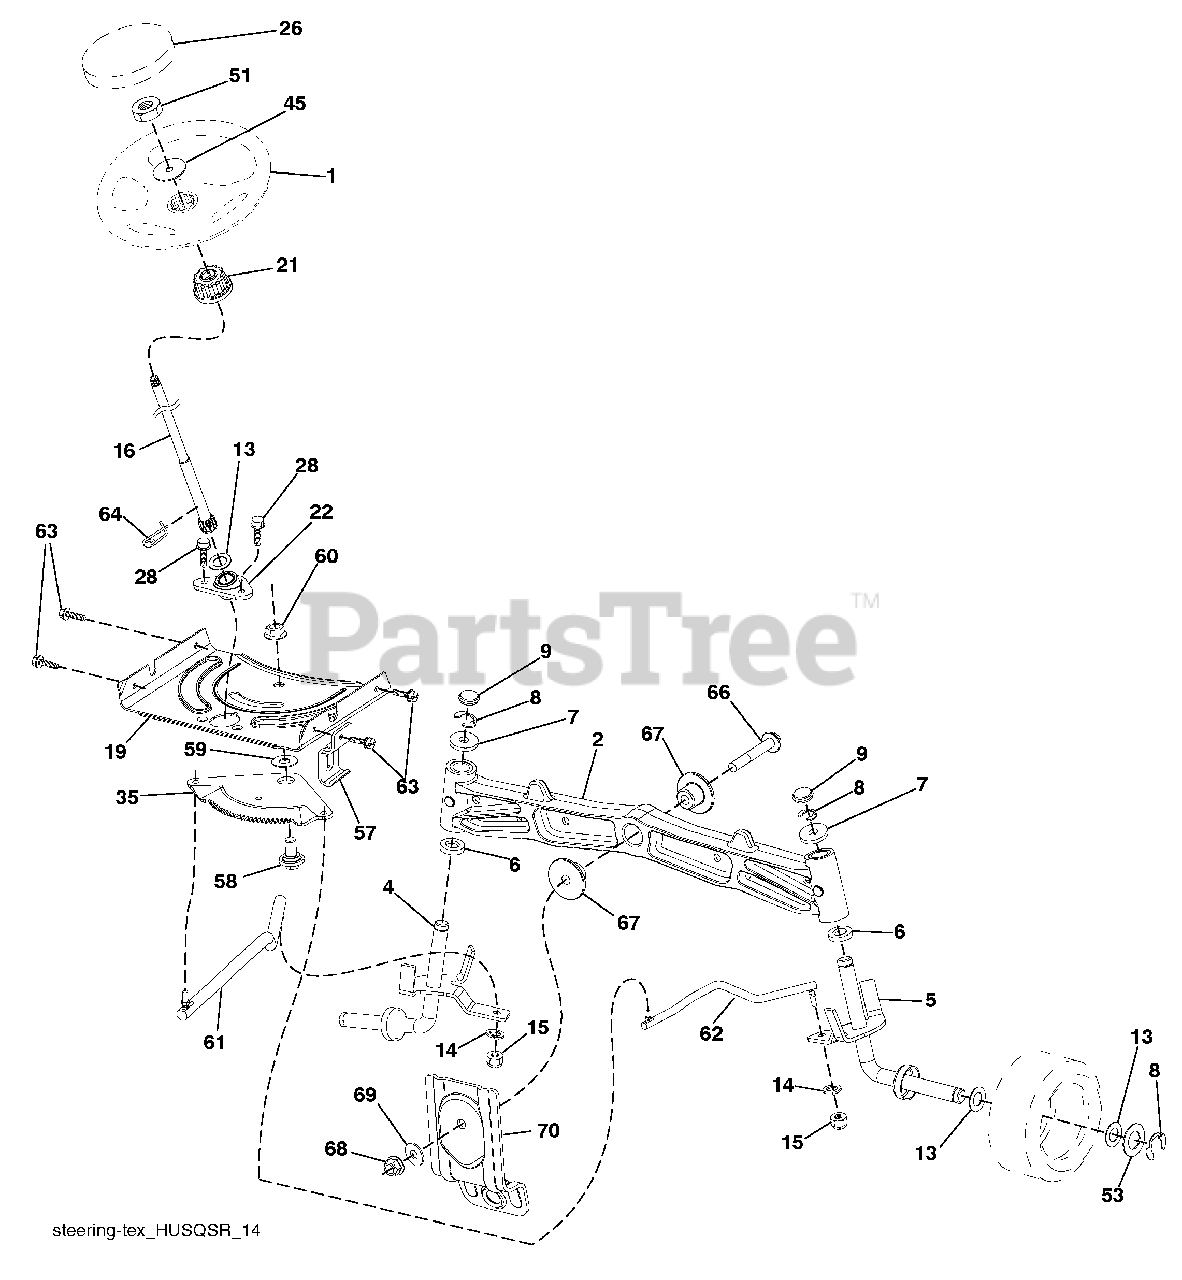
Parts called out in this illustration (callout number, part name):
1	Wheel, Steering
2	Axle Asm., Front
4	Spindle Asm., LH
5	Spindle Asm., RH
6	Bearing, Race Thrust Harden
7	Washer 25/32 x 1-5/8 x 16 Ga.
8	Ring, Klip #T5304-75
9	Cap, Spindle
13	Washer 25/32 x 1-1/4 x 16 Ga.
14	Washer, Lock Hvy Hlcl Spr 3/8
15	Nut, Crown Lock 3/8-24 unf
16	Shaft Steering
19	Plate Steering
21	Adapter, Wheel Steering
22	Strg. Supt. lower
26	Insert, Wheel Steering
28	Screw 3/8-16 x 3/4
35	Gear, Sector Plate
45	Washer 9/16 x 2-3/8 x 12 Ga.
51	Nut Hex Jam Toplock 1/2-20 unf
53	Washer Hardened .793 x 1.637 x .060
57	Bracket Upstop
58	Bolt Shoulder Sector Pivot CFM
59	Washer Thrust Sector Steering
60	Nut Flange Lock 5/8-11
61	Draglink LH
62	Draglink, RH
63	Screw 5/16-18 x 3/4
64	Retainer Clip Spring Steering
66	Bolt Hex Fghd 7/16-14 x 3 Serr
67	Bushing PM Front Axle
68	Nut Lock Flange 7/16-14 Gr. 5
69	Washer 1.5 x .505 x .118
70	Bracket Deck Susp. Front
